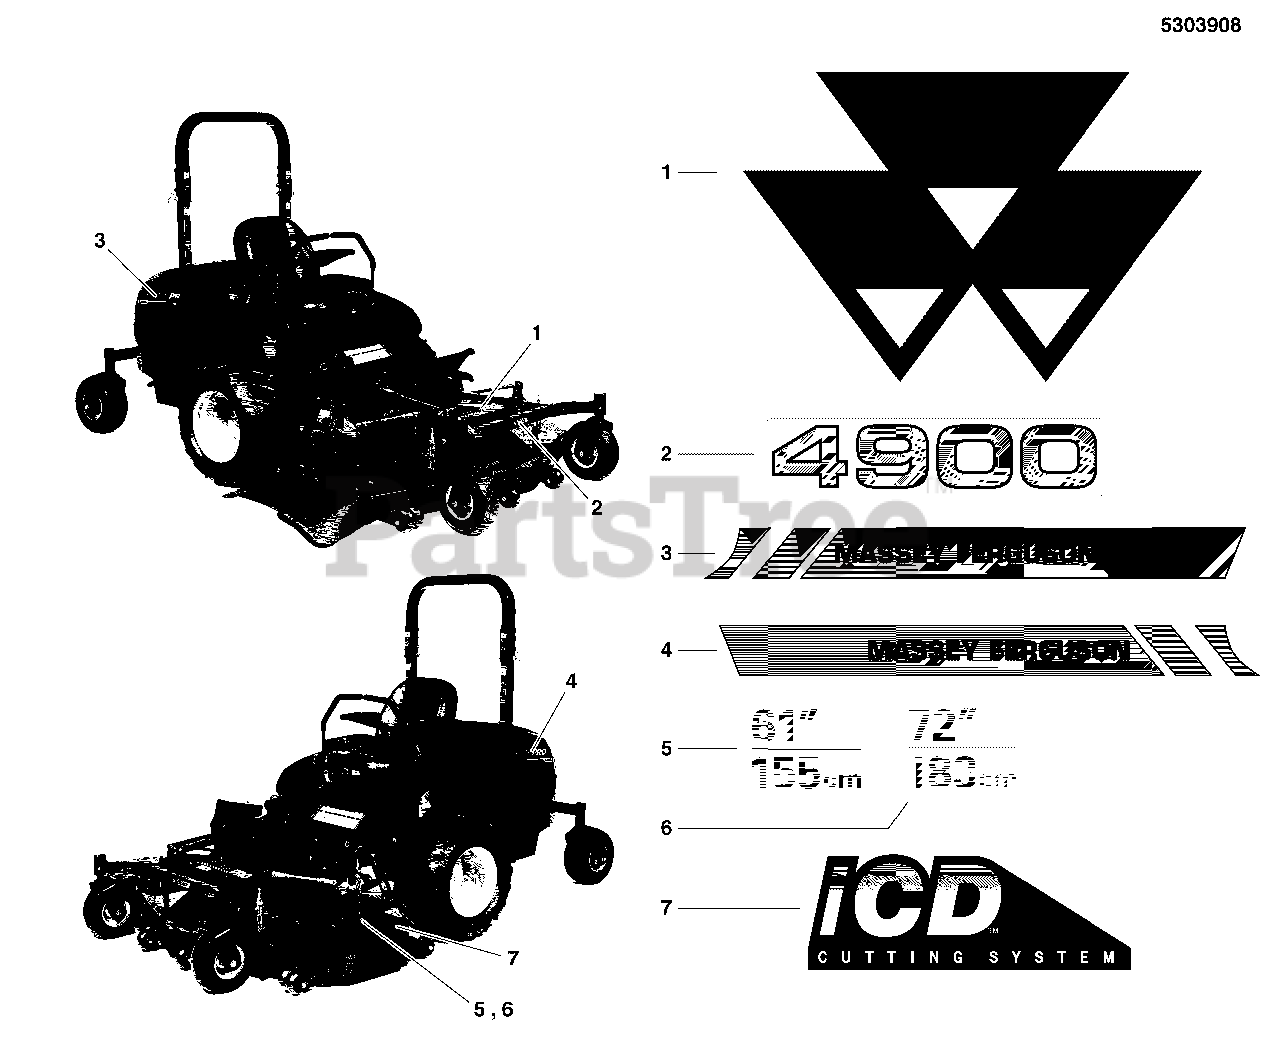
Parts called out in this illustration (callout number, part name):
1	DECAL, MASSEY LOGO SIDE PANEL
2	DECAL, 4900
3	DECAL, LH STRIPE, 4900
4	DECAL, RH STRIPE, 4900
5	DECAL, MOWER WIDTH 61IN/155CM
6	DECAL, MOWER WIDTH, 72IN/183CM
7	DECAL, iCD CUTTING SYSTEM
